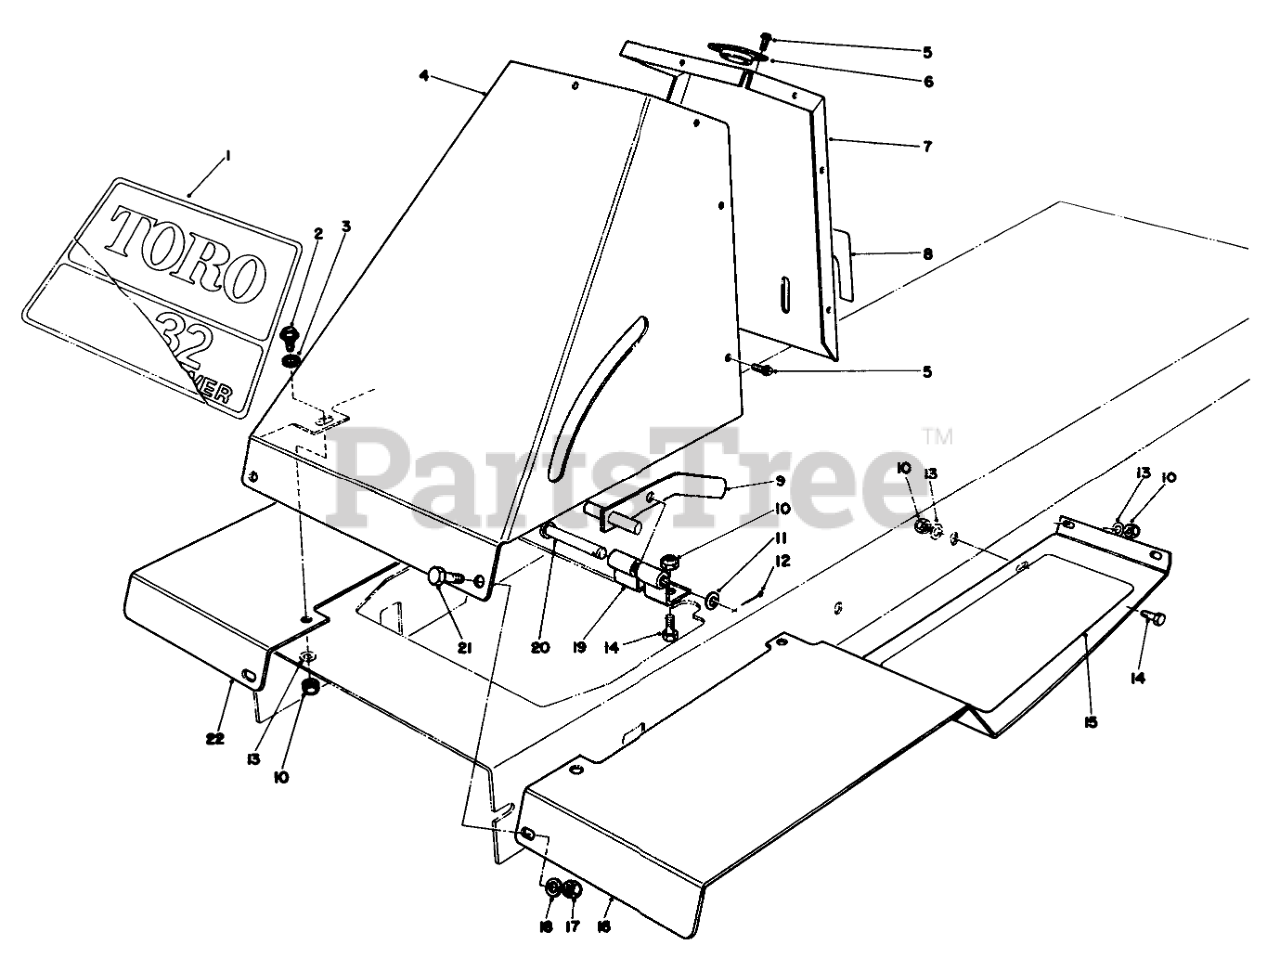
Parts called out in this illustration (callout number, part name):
1	Decal-Toro 832
2	SCREW-SHOULDER
3	SPACER
4	Tower-Front
5	SCREW-HWHTF
6	GUIDE-STRG SHAFT
7	Tower-Rear
8	PARK BRAKE DECAL
9	PARKING BRAKE WA B
10	NUT-LOCK, NI
11	WASHER-FLAT
12	PIN-COTTER
13	WASHER-PLAIN
14	SCREW-HH
15	FOOT TREAD L.H.
16	Footrest-LH
17	NUT-LOCK, CONE
18	WASHER-FLAT
19	Bracket-Parking Brake
20	PIN-CLEVIS
21	SCREW-HH
22	Footrest-RH.
